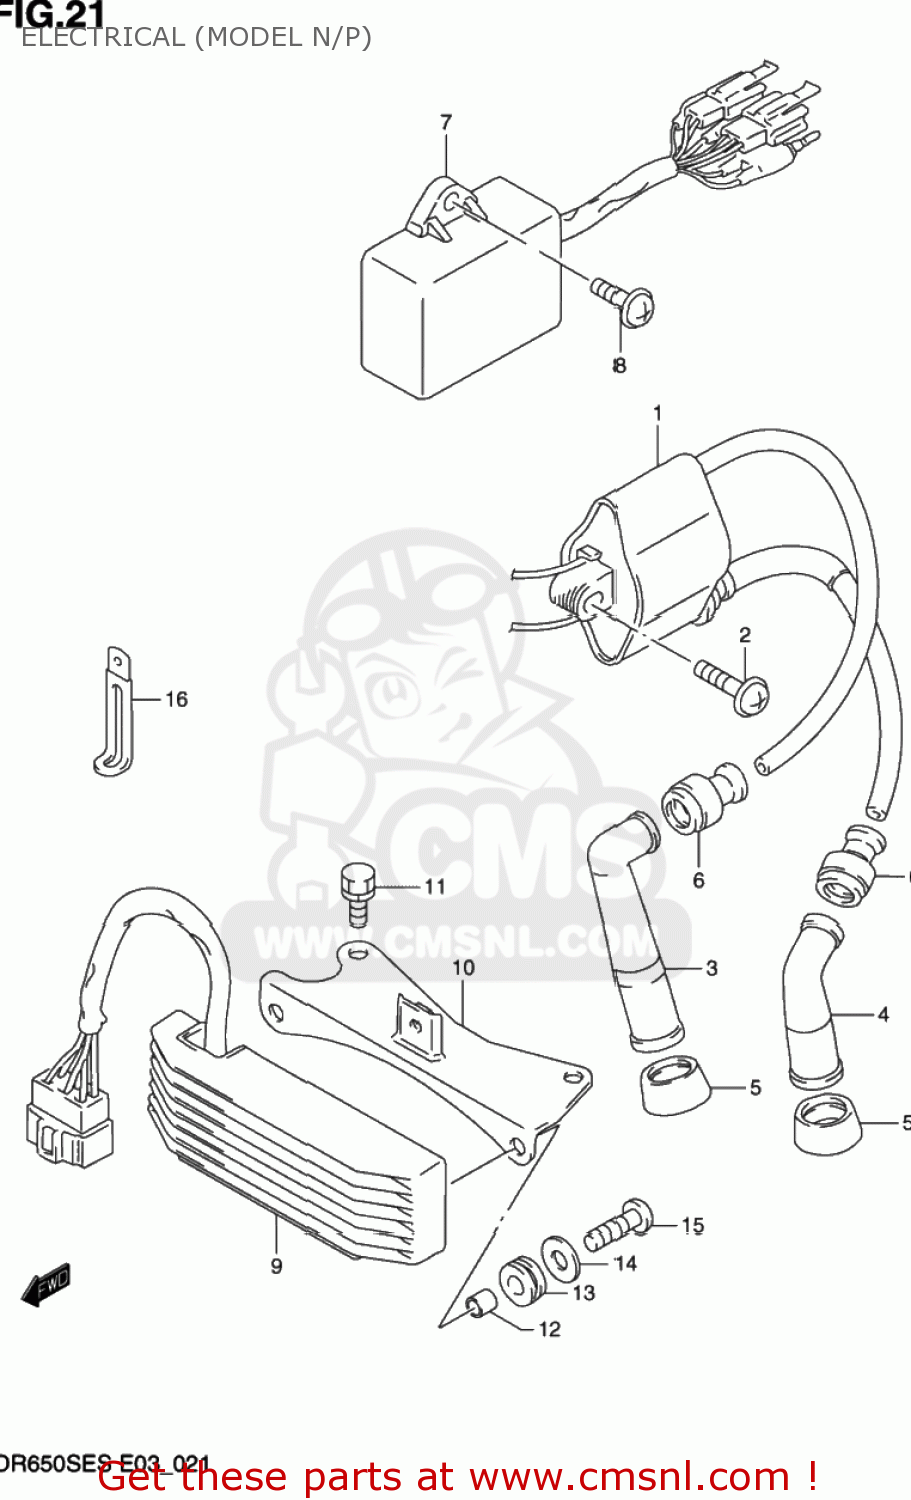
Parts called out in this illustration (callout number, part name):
1	COIL ASSY,IGNITION
2	SCREW
3	CAP ASSY,SPARK PLUG
4	CAP,SPARK PLUG
5	SEAL,SPARK PLUG CAP
6	SEAL,HIGH TENSION CORD
7	CDI UNIT
8	SCREW
9	RECTIFIER ASSEMBLY
10	BRACKET,RECTIFIER
11	BOLT 6X12
12	SPACER (6.1X8X9.5)
13	CUSHION
14	WASHER(6.5X18X1)
15	SCREW, CENTER
16	CLAMP
